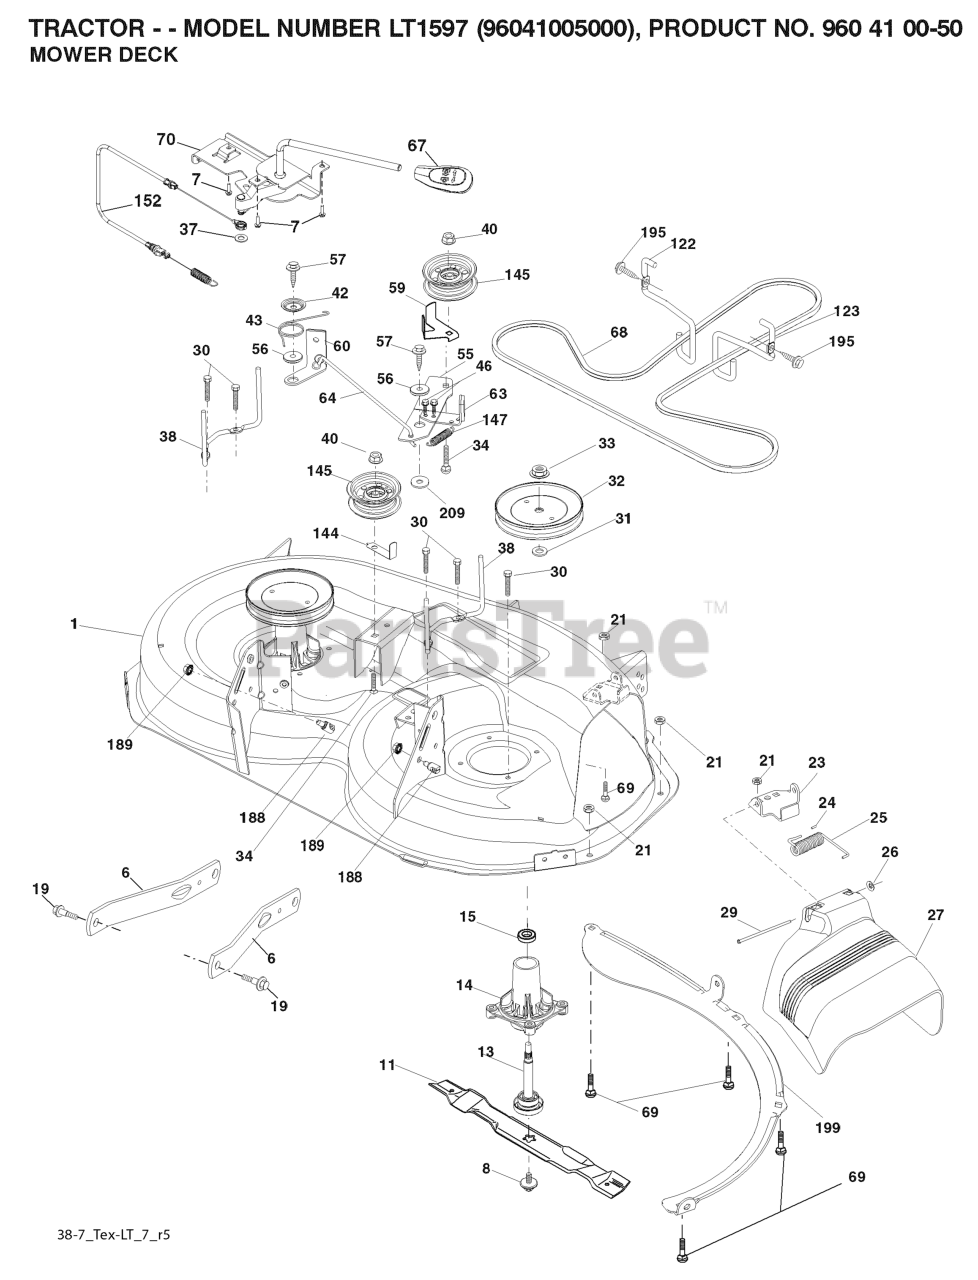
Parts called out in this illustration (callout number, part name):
1	HOUSING
6	ARM.SUSPENSION.MOWER.R
7	SCREW.#10 X 0.750.BOS
8	BOLT.WASHER.ASM.7/16-2
11	BLADE 38" PREMIUM
13	SHAFT.ASM.MDRL.N/GREASE.38
14	RP.HOUSING.MANDREL.4PT.
19	BOLT.SHOULDER
21	LOCKNUT
23	BRKT.DEFLECTOR.38"2005+
24	CAP-SLEEVE LT
25	SPRING.TORSION.DEFLECT
26	NUT PUSH M
27	SHIELD.DEFLECTOR.MWR.38-7/97CM
29	ROD.HINGE
30	SCREW, WASHER HEAD
31	WASHER.SPACER.MANDREL
32	PULLEY.MANDREL.5.0.PD.38"
33	NUT.FLANGE.LOCK.TOP
34	BOLT.3/8-16X1.50
37	WASHER
38	KEEPER BELT LH MANDREL
40	NUT LOCK FLG 3/8-16 UNC
42	SPRING.TORSION.BRAKE
43	SRPING.TORSION.RETAINE
46	SCREW.1/4-20X5/8
56	SPACER.RETAINER
57	SCREW 3/8-16X1
59	GUARD, BELT
60	ARM BRAKE MOWER RH 38"
62	BOLT.3/8-16X1.50
63	RP ARM.BRAKE.MOWER.38"LH.TEX
64	LINK BRAKE
67	HANDLE.CLUTCH.CABLE.LT
69	BOLT
70	CLUTCH.ASM.MANUAL.LT.PRED
122	KEEPER BELT ENGINE LH
123	KEEPER BELT RH
144	KEEPER BELT
145	PULLEY.IDLER.48"PRIMARY
147	SPRING RETURN
152	CLUTCH CABLE
188	STUD.FASTNER.W/ANTI-ROTATE
189	NUT LOCK HEX FLANGE 5/16-18
195	SCREW, 3/8-16X3/4
199	BAFFLE.VORTEX.FRONT.38"
209	WASHER 12/32X2X10GA
